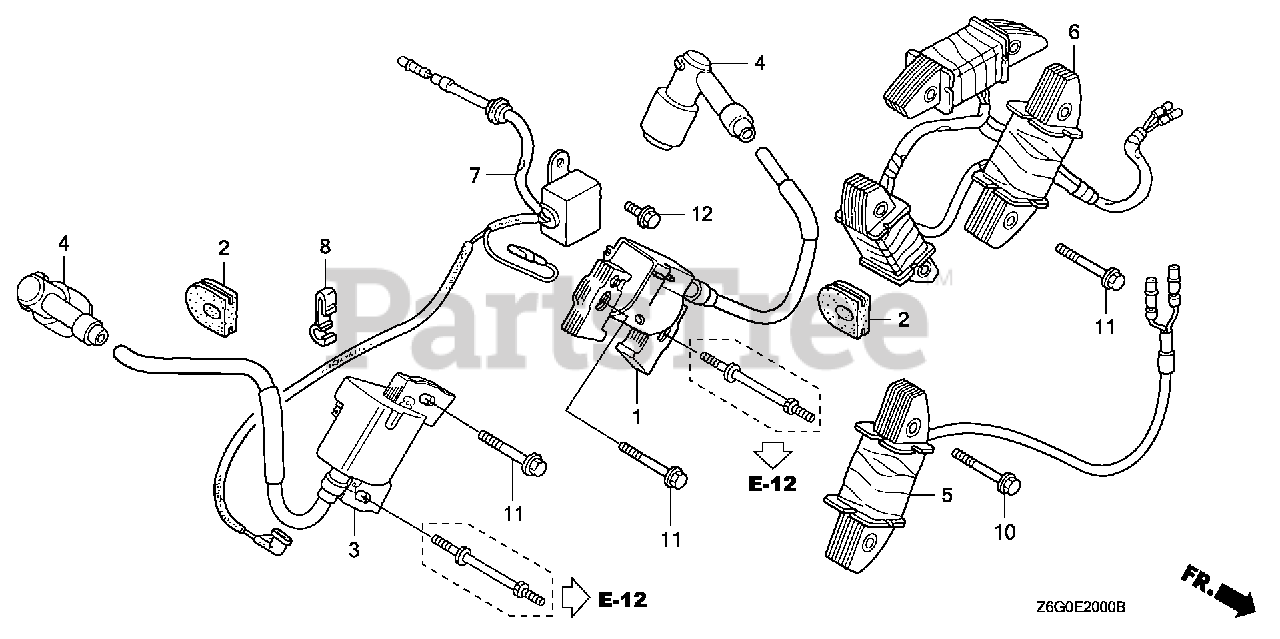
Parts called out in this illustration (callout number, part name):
1	COIL ASSY., IGNITION (200MM) (BLACK) (L. SIDE)
2	GROMMET, IGNITION WIRE
3	COIL ASSY., IGNITION (215MM) (GRAY) (R. SIDE)
4	CAP ASSY., NOISE SUPPRESSOR
6	COIL ASSY., CHARGE (12V/20A)
7	DIODE ASSY., ENGINE STOP
8	CLAMP, WIRE
11	BOLT, FLANGE (6X32) (CT200)
12	BOLT, FLANGE (6X8)
